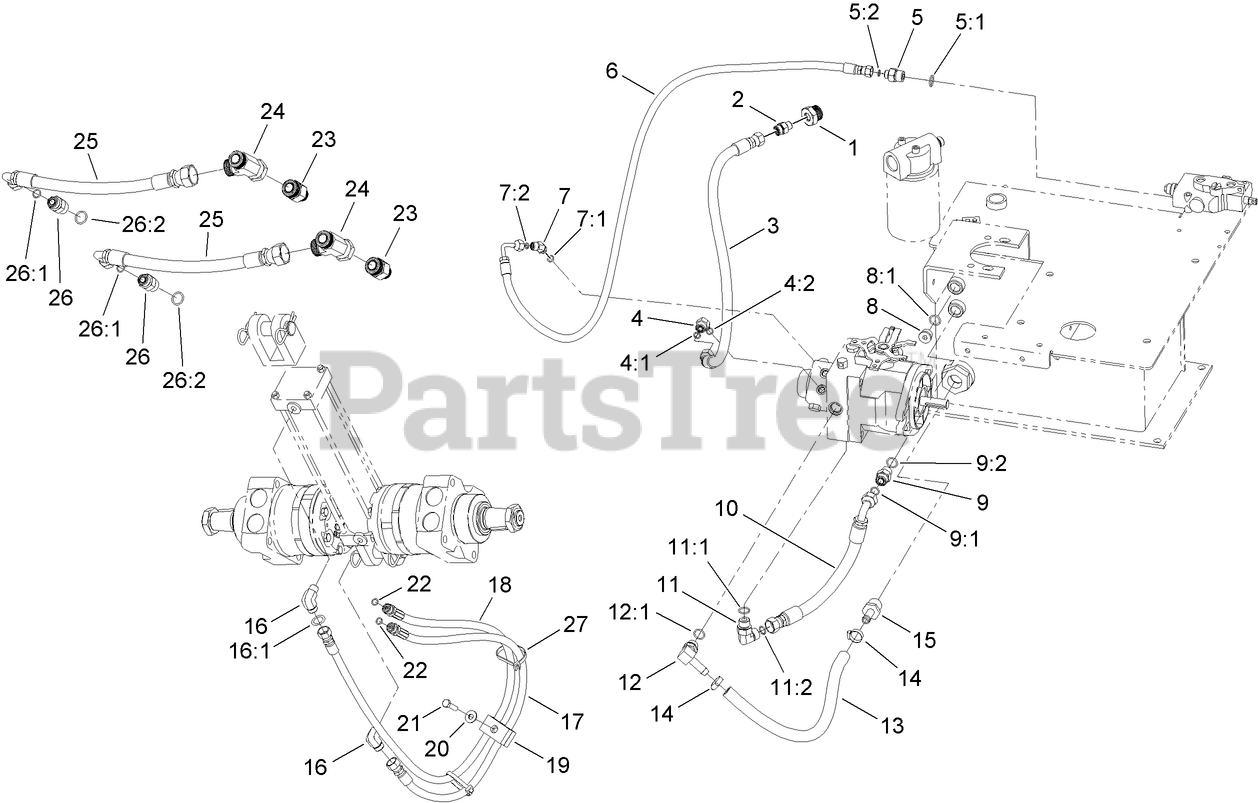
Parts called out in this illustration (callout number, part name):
1	FITTING-HYD
2	FITTING-HYD
3	HYD HOSE ASM
4	ELBOW-45 DEG
4:1	O-RING
4:2	O-RING
5	FITTING-STR
5:1	O-RING
5:2	O-RING
6	HYD HOSE ASM
7	FITTING-HYD, 45 DEG
7:1	O-RING
7:2	O-RING
8	PLUG-HEX
8:1	O-RING
9	FITTING-STRAIGHT
9:1	O-RING
9:2	O-RING
10	HYD HOSE ASM
11	FITTING-ELBOW-90 DEG
11:1	O-RING
11:2	O-RING
12	FITTING-ELB 90
12:1	O-RING
13	HOSE-RETURN
14	CLAMP-DRIVE, WORM
15	FITTING-HYD
16	FITTING-ELBOW, 90
16:1	O-RING
17	HYD HOSE ASM
18	HYD HOSE ASM
19	CLAMP-TWIN
20	WASHER-FLAT
21	SCREW-HH
22	O-RING
23	FITTING-HYD
24	FITTING-HYD
25	HYD HOSE ASM
26	FITTING-STRAIGHT
26:1	O-RING
26:2	O-RING
27	TIE-PLASTIC
